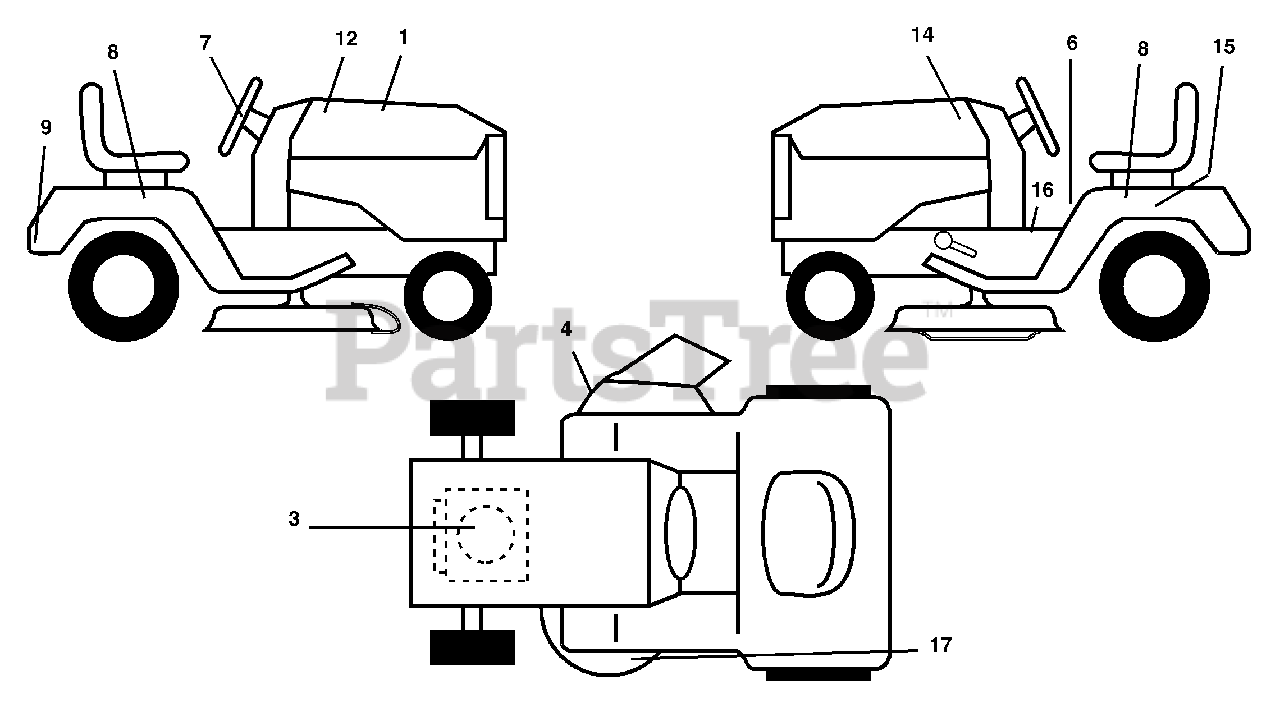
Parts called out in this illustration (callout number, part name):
1	NPR Decal Replace
3	Decal, Engine HP
4	Decal Warning
6	Decal, Fender Danger English
7	Decal Ins Str Wh
8	Decal, Fender 5 Sp.
9	Decal Fender
12	Decal, Hood RH
14	Decal, Hood LH
15	Decal, Caution, Battery
16	Decal, Oper Inst.
17	Decal, V-Belt Sch.
